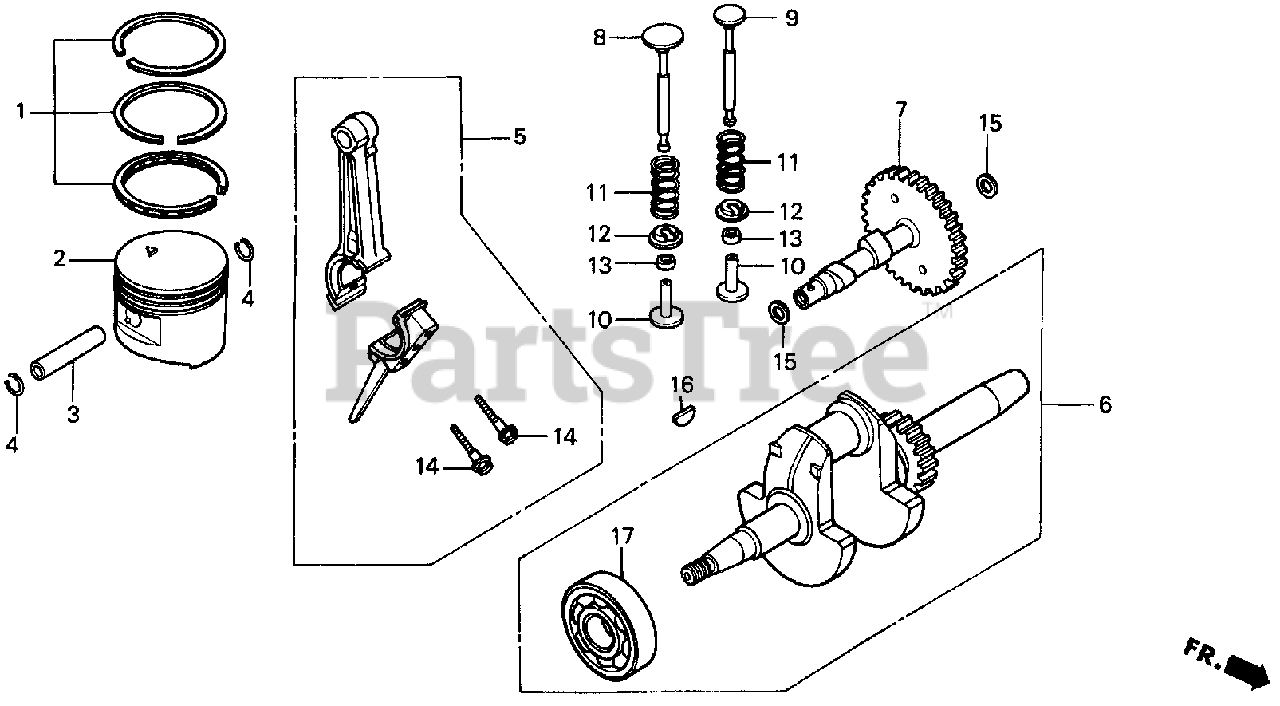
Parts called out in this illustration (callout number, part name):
1	RING SET, PISTON (STD)
1	RING SET, PISTON (OVER SIZE)
2	PISTON (STD)
2	PISTON (OVER SIZE) (0.25)
2	PISTON (OVER SIZE) (0.50)
2	PISTON (OVER SIZE) (0.75)
3	PIN, PISTON
4	CLIP, PISTON PIN (10MM)
5	ROD ASSY., CONNECTING
6	CRANKSHAFT
7	CAMSHAFT
8	VALVE, IN.
9	VALVE, EX.
10	LIFTER, VALVE
11	SPRING, VALVE
12	RETAINER, VALVE SPRING
13	ADJUSTER, TAPPET CLEARANCE (3.15)
13	ADJUSTER, TAPPET CLEARANCE (3.25)
13	ADJUSTER, TAPPET CLEARANCE (3.34)
13	ADJUSTER, TAPPET CLEARANCE (3.43)
13	ADJUSTER, TAPPET CLEARANCE (3.52)
13	ADJUSTER, TAPPET CLEARANCE (3.61)
13	ADJUSTER, TAPPET CLEARANCE (3.72)
13	ADJUSTER, TAPPET CLEARANCE (3.82)
14	BOLT, CONNECTING ROD
15	WASHER (12MM)
16	KEY, WOODRUFF (3MM)
17	BEARING, RADIAL BALL (6203)
